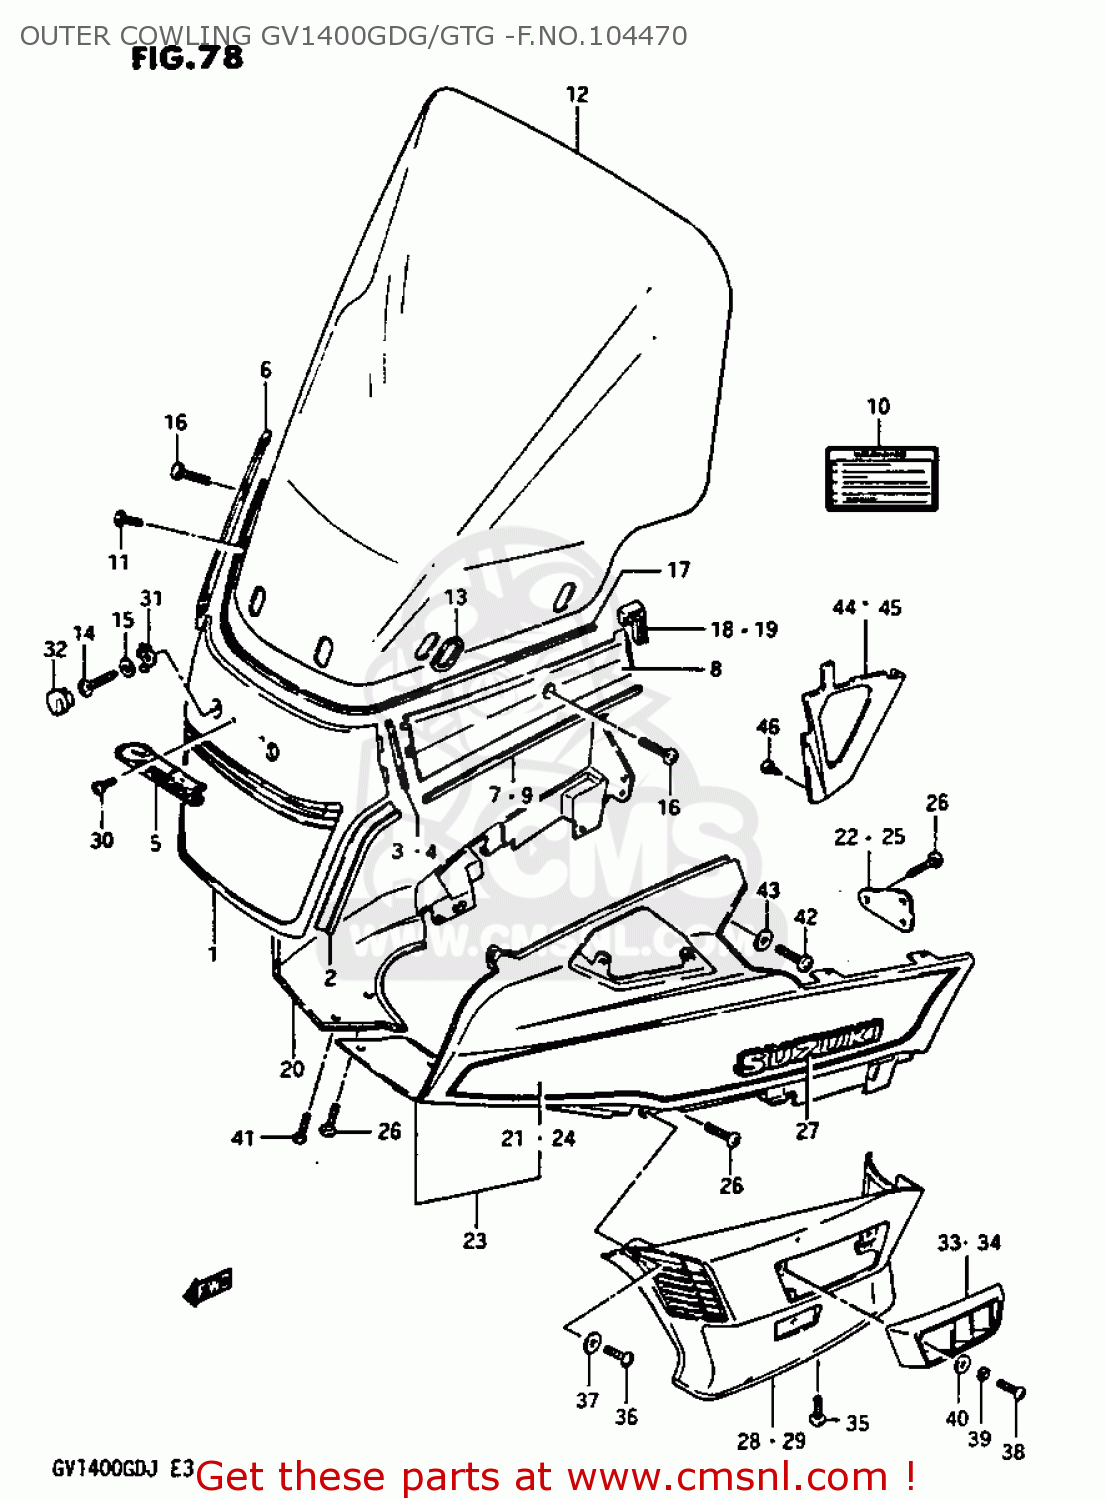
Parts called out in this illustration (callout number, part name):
1	COVER,COWLING,FRONT,CENTER
2	MOLDING,FRONT COVER,LOWER
3	CUSHION,WINDSHEILD
4	PLATE,WINDSHEILD
5	EMBLEM,COWLING,FRONT
6	COVER,COWLING,FRONT,RIGHT
7	MOLDING,FRONT COVER SIDE
8	COVER,COWLING,FRONT,LEFT
9	MOLDING,FRONT COVER SIDE
10	LABEL (WARNING SCREEN)
11	SCREW
12	SCREEN ASSY,COWLING
13	WASHER,SCREEN
14	SCREW
15	WASHER
16	SCREW
17	SEAL,FRONT COVER,CENTER
18	CAP,COWLING FRONT COVER END
19	CAP,COWL FR COVER END,L
20	BODY,COWLING,RIGHT
21	TAPE SET,COWLING
22	BRACKET,COWLING BODY,RIGHT
23	BODY,COWLING,LEFT
24	TAPE SET,COWLING
25	BRACKET,COWLING BODY,RIGHT
26	SCREW
27	EMBLEM,COWLING SIDE,LEFT
28	COVER SET,COWLING SIDE
29	COVER ASSEMBLY,COWLING SIDE,LEFT
30	SCREW
31	PLATE,FR COVER LOCK
32	CAP,FR COVER
33	LOUVER,SIDE COVER,RIGHT
34	LOUVER,SIDE COVER,LEFT
35	SCREW (M6X1X16)
36	SCREW
37	WASHER (4.3X13X0.80)
38	SCREW 4X16
39	LOCK WASHER
40	WASHER
41	SCREW
42	SCREW
43	WASHER
44	UNDER COVER, FRAME
45	COVER,COVER FRAME,UPPER
46	SCREW
